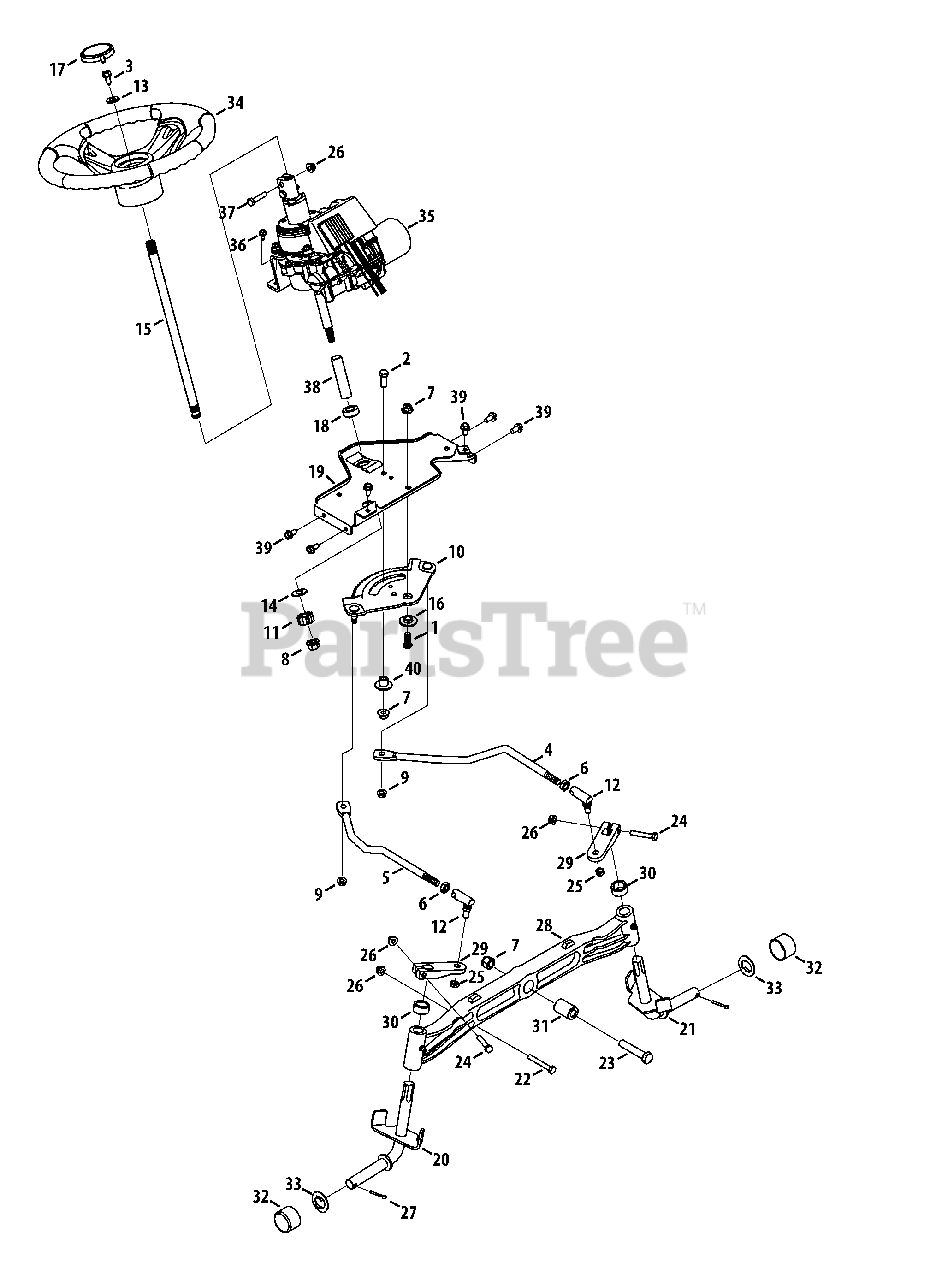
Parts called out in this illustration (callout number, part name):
1	Hex Screw, 3/8-16, 1.00, Gr5, Spec
2	Hex Screw, 3/8-16, 1.25, Gr5
3	Hex Screw, 5/16-18, .875, Gr5, Lock
4	Link, Drag LH
5	Link, Drag RH
6	Nut, Jam, 7/16-20, Gr2
7	Nut, Flange Lock, 3/8-16, Grf,
8	Nut, Flange Lock, 7/16-20, Grb, Lock
9	Nut, Flange Lock, 5/16-18, Gr5, Sd Lk
10	Gear, Steering
11	Gear, Pinion, Steering
12	Ball Joint, 7/16-20, Lock
13	Washer, Flat, .406 x .875 x .105
14	Washer, Flat, .51 x 1.12 x .06
15	Shaft, Steering, .625 OD x 14, Cub
16	Spacer, Shoulder, .385x 1.25 x .3025
17	Cover, Steering Wheel, Cub Cadet
18	Bearing, Flange, Hex 5/8 Pm
19	Bracket, Support, Steering
20	Axle Ass’y, RH .750 Dia.
21	Axle Ass’y, LH .750 Dia.
22	Hex Screw, 5/16-18, 2.25, Gr5, Std
23	Hex Screw, 3/8-16, 2.50, Gr5, Std
24	Hex Screw, 5/16-18, 1.75, Gr5, Std
25	Nut, Hex Lock, 3/8-24, Grb
26	Nut, Flange Lock, 5/16-18, Grf
27	Pin, Cotter, 5/32, 1.25
28	Axle, Pivot Bar, Cast
29	Steering, Block
30	Spacer, .71 ID x .125 OD x .56
31	Spacer, .385 x 1.00 x 1.5075
32	Cap, Bumper
33	Washer, Flat, .350 x 1.559 x .062
34	Wheel, Steering, 3 Spoke, Softgrip
35	Transmission Assembly, EPS
36	Screw, Self-tapping, 1/4-20 x .625
37	Hex Screw, 5/16-18 x 1.375, Gr5, Std
38	Spacer, .625 x .750 x 3.11
39	Screw, Self-tapping, 5/16-18, .750
40	Shoulder Spacer, .385 x 1.25 x .6525
